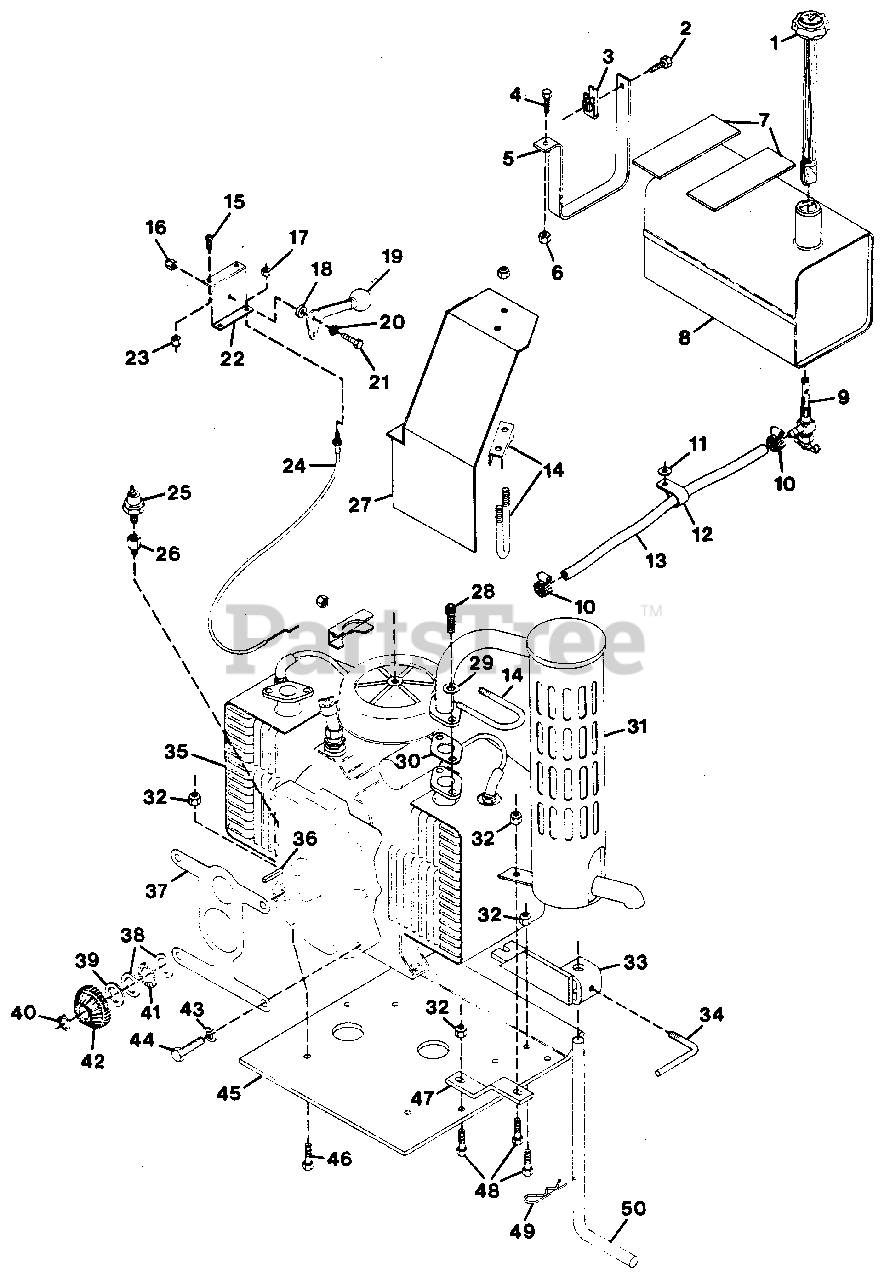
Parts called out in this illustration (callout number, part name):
1	Gauge, Fuel
2	Bolt, Hex 5/16-18x.75
3	Nut, Retainer
4	Bolt, Hex 5/16-18x1.25
5	Strap, Gas Tank
6	Nut, Lock 5/16-18
7	Pad, Gas Tank
8	Tank, Fuel
9	Valve and Strainer
10	Clamp, Hose
11	Washer, Flat .344x.688x.065
12	Clamp, Nylon
13	Fuel Line, 3' Long
14	Clamp, Muffler
15	Screw, Mach 10-32x.50 P/Hd
16	Nut, Lock 1/4-28
17	Nut, Hex 1/4-20
18	Washer, Friction
19	Assembly, Knob & Lever
20	Washer, Spring
21	Bolt, Hex 1/4-28x.75
22	Bracket, Throttle
23	Nut, Lock 10-32
24	Assembly, Conduit
25	Switch, Pressure
26	Reducer
27	Weldment, Heat Shield L.H.
27	Weldment, Heat Shield R.H.
28	Screw, Cap 5/16-18x.75 S/Hd
29	Washer, Lock 5/16 Reg.
30	Gasket, Exhaust
31	Muffler, Pro Master-60
32	Nut, Lock 3/8-16
33	Assembly, Stand Support
34	Handle, Adjusting
35	Engine, 18 HP
35	Engine, 20 HP
36	Key, Square .250x1.250
37	Gasket, Engine to Transmission
38	Race, Brg Thst 1.125x1.750x.125
39	Race, Bearing Thrust .030
40	Ring, Retaining 1.125 Shaft
41	Brg, Thrust 1.127x1.740x.078
42	Gear, Spur and Bevel Input
43	Washer, Lock 1/2 Reg.
44	Bolt, Hex 1/2-13x1.75
45	Plate, Skid
46	Bolt, Hex 3/8-16x1.25
47	Bracket, Muffler
48	Bolt, Hex 3/8-16x1.12
49	Pin, Hair
50	Assembly, Kick Stand
